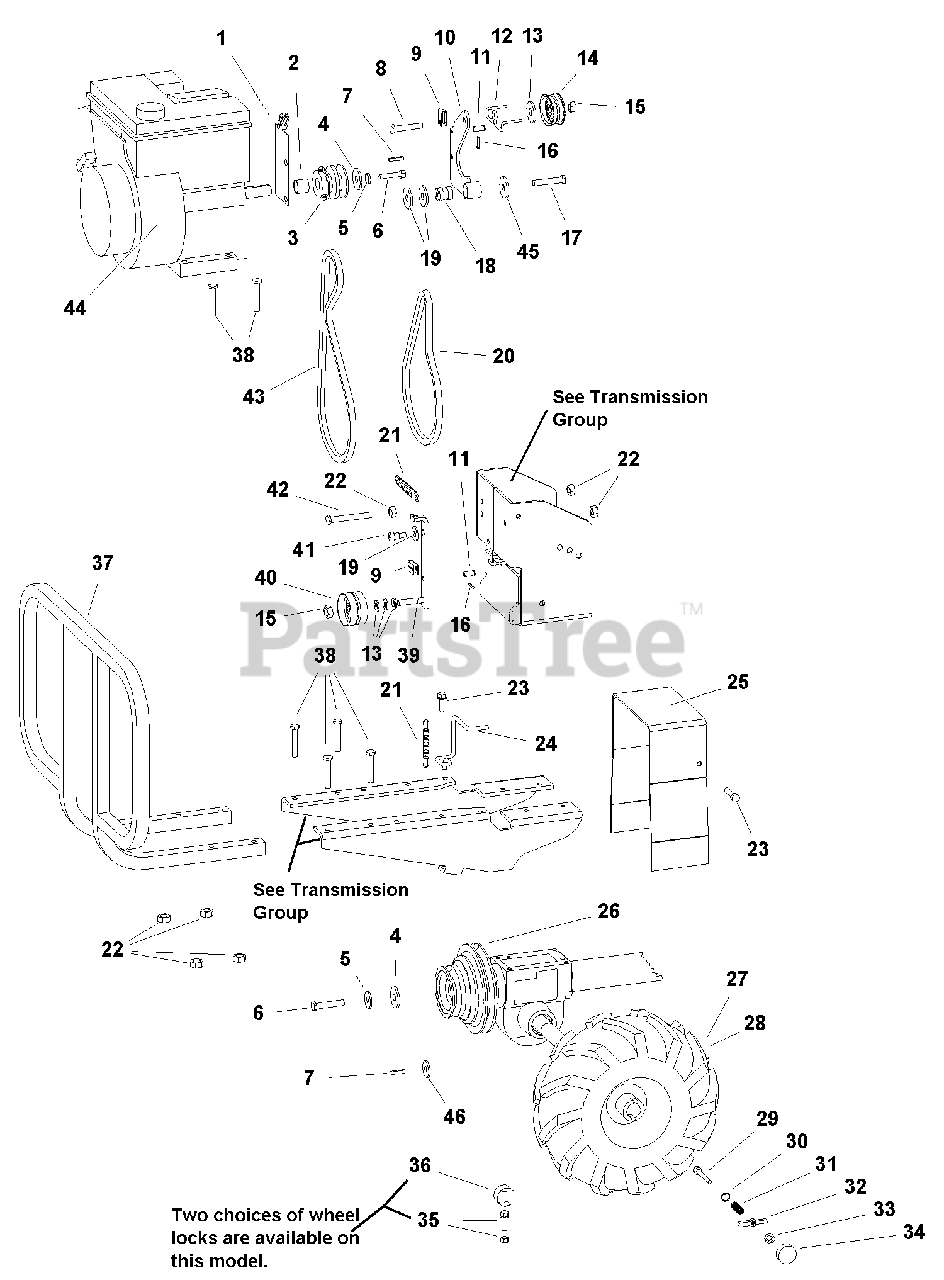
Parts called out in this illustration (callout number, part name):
1	BRACKET, Engine
2	SPACER, Engine
3	PULLEY, Engine 2 Groove
5	LOCKWASHER, Spring 5/16
6	CAPSCREW, Hex Head, 5/16-24 x 3/4
7	KEY, Parallel
8	CAPSCREW, Hex Head, 3/8-24 x 2
9	YOKE, Cable
11	PIN, LINK Forward/Reverse
12	GUIDE, Belt Reverse
13	WASHER, 3/8
14	PULLEY, Idler Reverse
15	NUT, Hex Center Lock, 3/8-16
16	PIN, Cotter
17	BOLT, Flat Head, 5/16-24 x 1-1/2
19	WASHER, 5/16
20	V-BELT, Forward
21	SPRING, Idler Arm
22	NUT, Hex Flange 5/16-18
23	BOLT, Hex Flange Head, 5/16-18 x 3/4
24	GUIDE, Belt Forward
25	COVER, Belt
26	PULLEY, Transmission 2 Groove
27	WHEEL & TIRE ASSEMBLY, Tiller LH
28	WHEEL & TIRE ASSEMBLY, Tiller RH
29	CAPSCREW, Hex Socket Head, 1/4-20 x 2-3/32
30	WASHER, 1/4
33	NUT, Hex KEPS 1/4-20
34	KNOB, Lock Out Set of Two
35	SETSCREW, Wheel Lockout
36	CLAMP, C Wheel Lockout
37	BUMPER, Guard
38	CAPSCREW, Hex Head, 5/16-18 x 1-3/4
39	ARM, Idler Forward
40	PULLEY, Forward Idler
41	SCREW, Hex Socket Shoulder, 5/16-18 x 3/8
42	CAPSCREW, Hex Head, 5/16-18 x 3-1/2
43	V-BELT, Reverse
44	ENGINE, 7HP Briggs & Stratton INTEK
45	WASHER, 3/8
